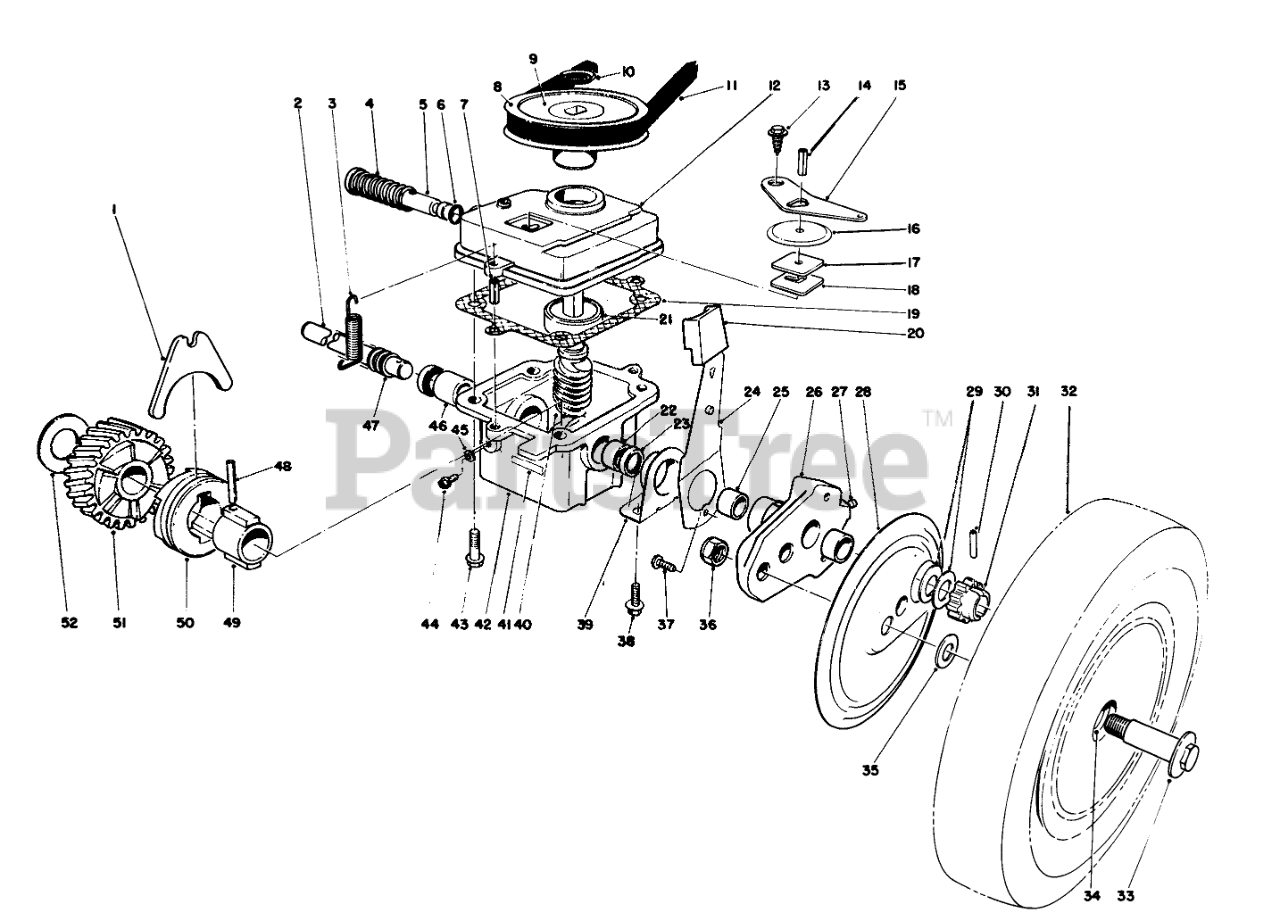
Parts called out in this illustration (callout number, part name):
1	SHIFTER FORK
2	DRIVE SHAFT
3	TENSION SPRING
4	SPRING
5	SHIFTER ROD
6	O-RING
7	3/16 X 1/2 ROLL PIN
8	PULLEY
9	DECAL
10	PUSH-ON 93-3236
11	V-Belt
12	GEAR CASE COVER
13	Screw
14	SPIROL PIN H D
15	SHIFTER ARM
16	DUST COVER
17	DUST FILTER
18	LATCH PLATE
19	GASKET
20	KNOB-ARM
21	BEARING
22	BUSHING
23	SEAL-OIL
24	SPRING ARM ASSY-FRONT
25	BUSHING
26	Arm-Pivot (Incl. Ref. #25 & 27)
27	FITTING-GREASE
28	WHEEL COVER
29	THRUST WASHER
30	Pin
31	PINION GEAR 15T
32	Wheel, Tire & Gear Assy (Incl. Ref. #34)
33	BOLT-WHEEL
34	BUSHING
35	WASHER
36	Nut
37	SCREW
38	SCREW-HWHTF
39	END CAP
40	Worm Shaft & Gear (Incl. Ref. #51)
41	DECAL
42	Gear Case (Incl. Ref. #22, 23 & 46)
43	Screw
44	NYLON SCREW
45	FILL PLUG GASKET
46	BUSHING
47	COVER-SHAFT, DRIVE
48	COIL PIN
49	SLEEVE
50	CLUTCH JAW
51	Gear-Helical
52	THRUST WASHER
